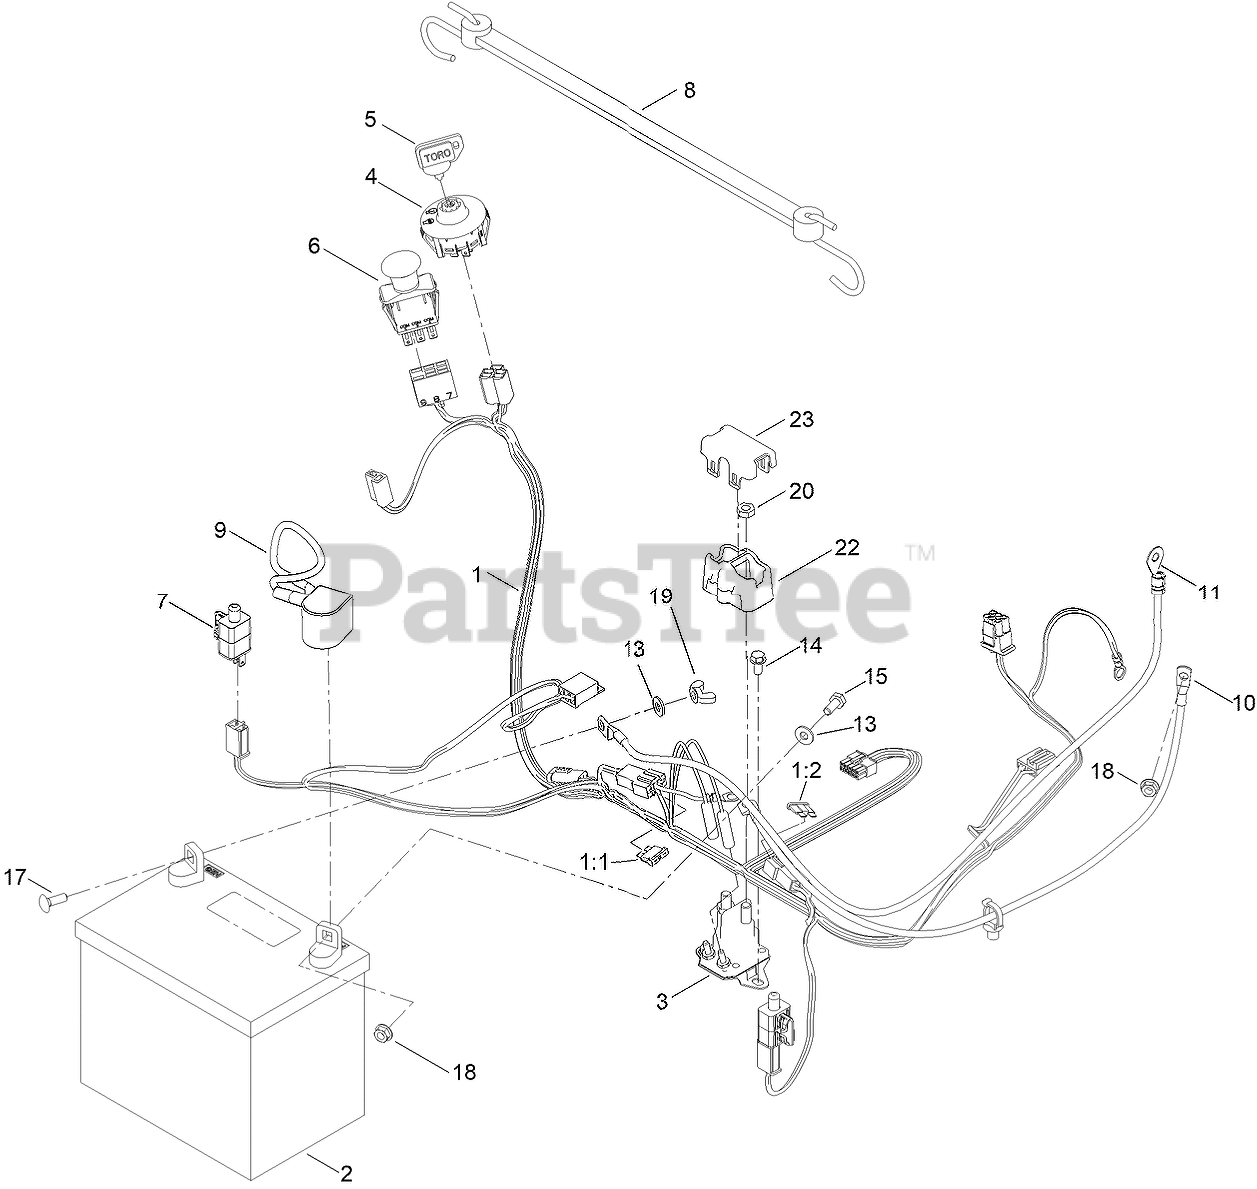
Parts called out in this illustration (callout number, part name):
1	HARNESS-WIRE
1:1	FUSE-BLADE, 15 AMP
1:2	FUSE-BLADE, 25 AMP
2	BATTERY
3	SOLENOID
4	SWITCH-IGNITION
5	KEY-IGNITION
6	SWITCH-PTO
7	SWITCH
8	STRAP-RUBBER
9	CABLE-BATTERY, POS
10	CABLE-BATTERY, RED (8 GAUGE)
11	CABLE-BATTERY, BLACK
13	WASHER-FLAT
14	SCREW-HWH
15	SCREW-HH
17	BOLT-CARR
18	NUT-HF
19	NUT-WING
20	NUT-JAM
22	COVER-SOLENOID
23	CAP-SOLENOID
